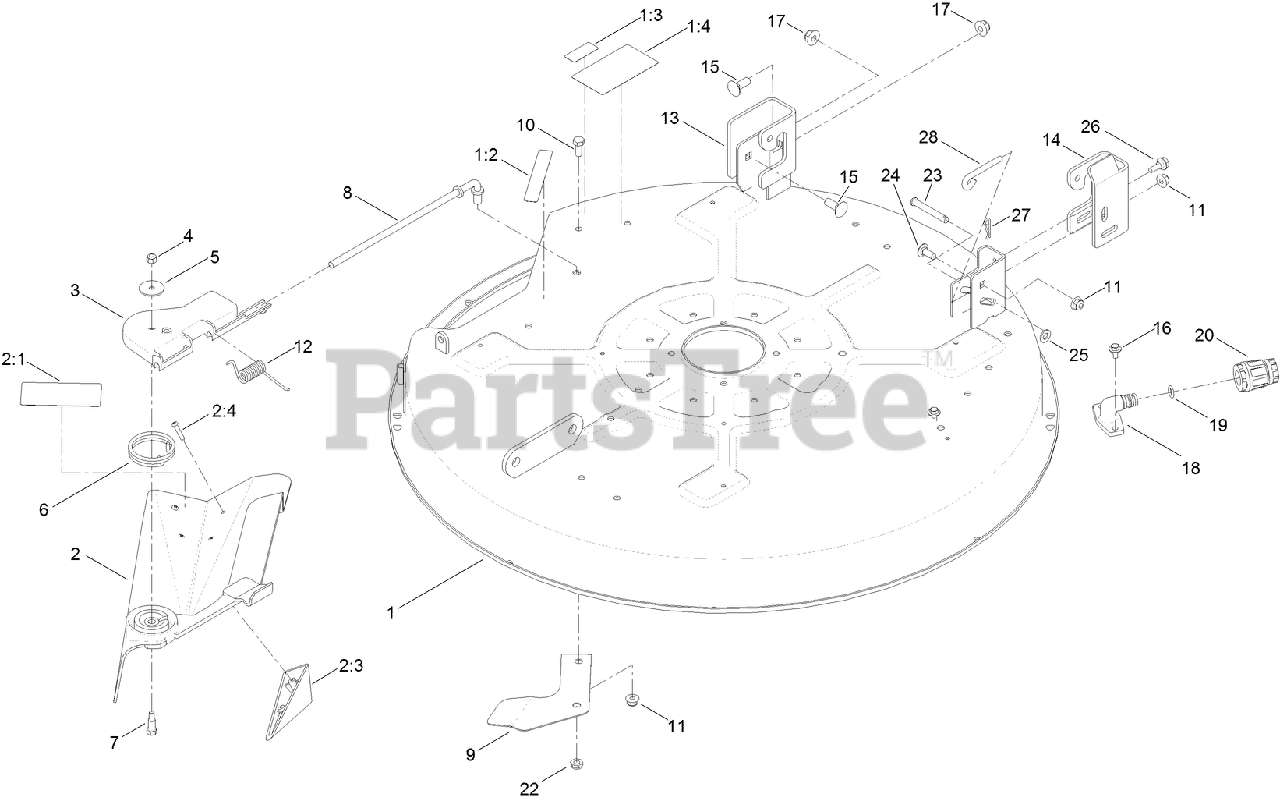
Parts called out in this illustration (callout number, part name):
1	32 INCH DECK AND DECAL ASM
1:2	DECAL-DANGER
1:3	DECAL-DANGER
1:4	DECAL-DANGER
2	32 INCH DEFLECTOR ASM
2:1	DECAL-DANGER
2:3	KICKER
2:4	SCREW-PPH
3	PIVOT-HINGE, DEFLECTOR
4	NUT-LOCK, NI
5	WASHER-FLAT
6	SPRING-TORSION
7	BOLT-SHOULDER
8	ROD-PIVOT
9	RAMP-DEFLECTOR
10	SCREW-HH
11	NUT-HF, NI
12	SPRING-TORSION
13	BRACKET-HANGER, RH
14	BRACKET-HANGER, LH
15	BOLT-CARR
16	SCREW-HHFTF
17	NUT-HF, NI
19	O-RING
20	CONNECTOR-HOSE
23	PIN-CLEVIS
24	SCREW-CARR
25	WASHER-PLAIN
26	SCREW-SHOULDER,HWH
27	PIN-COTTER
28	ROD-LEVEL, DECK
